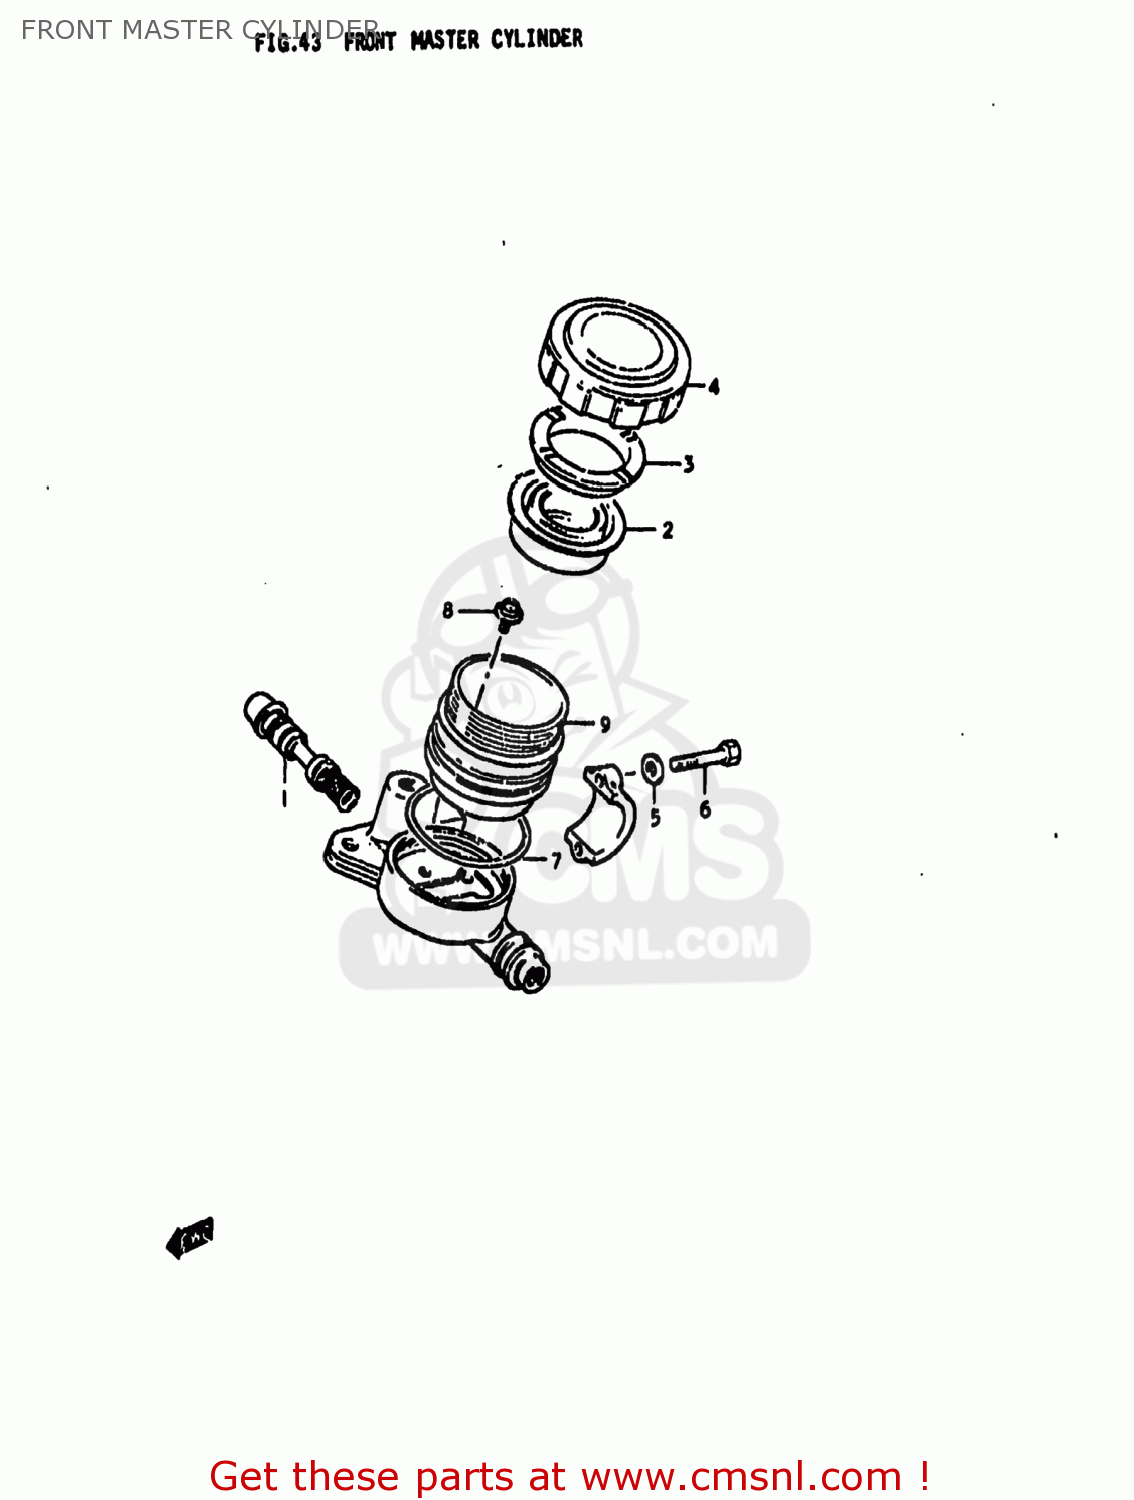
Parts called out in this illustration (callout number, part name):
1	CYLINDER ASSEMBLY,MASTER
2	DIAPHRAGM
3	PLATE,DIAPHRAGM
4	CAP
5	WASHER
6	BOLT
7	O RING
8	SCREW,MASTER CYLINDER
9	RESERVOIR
